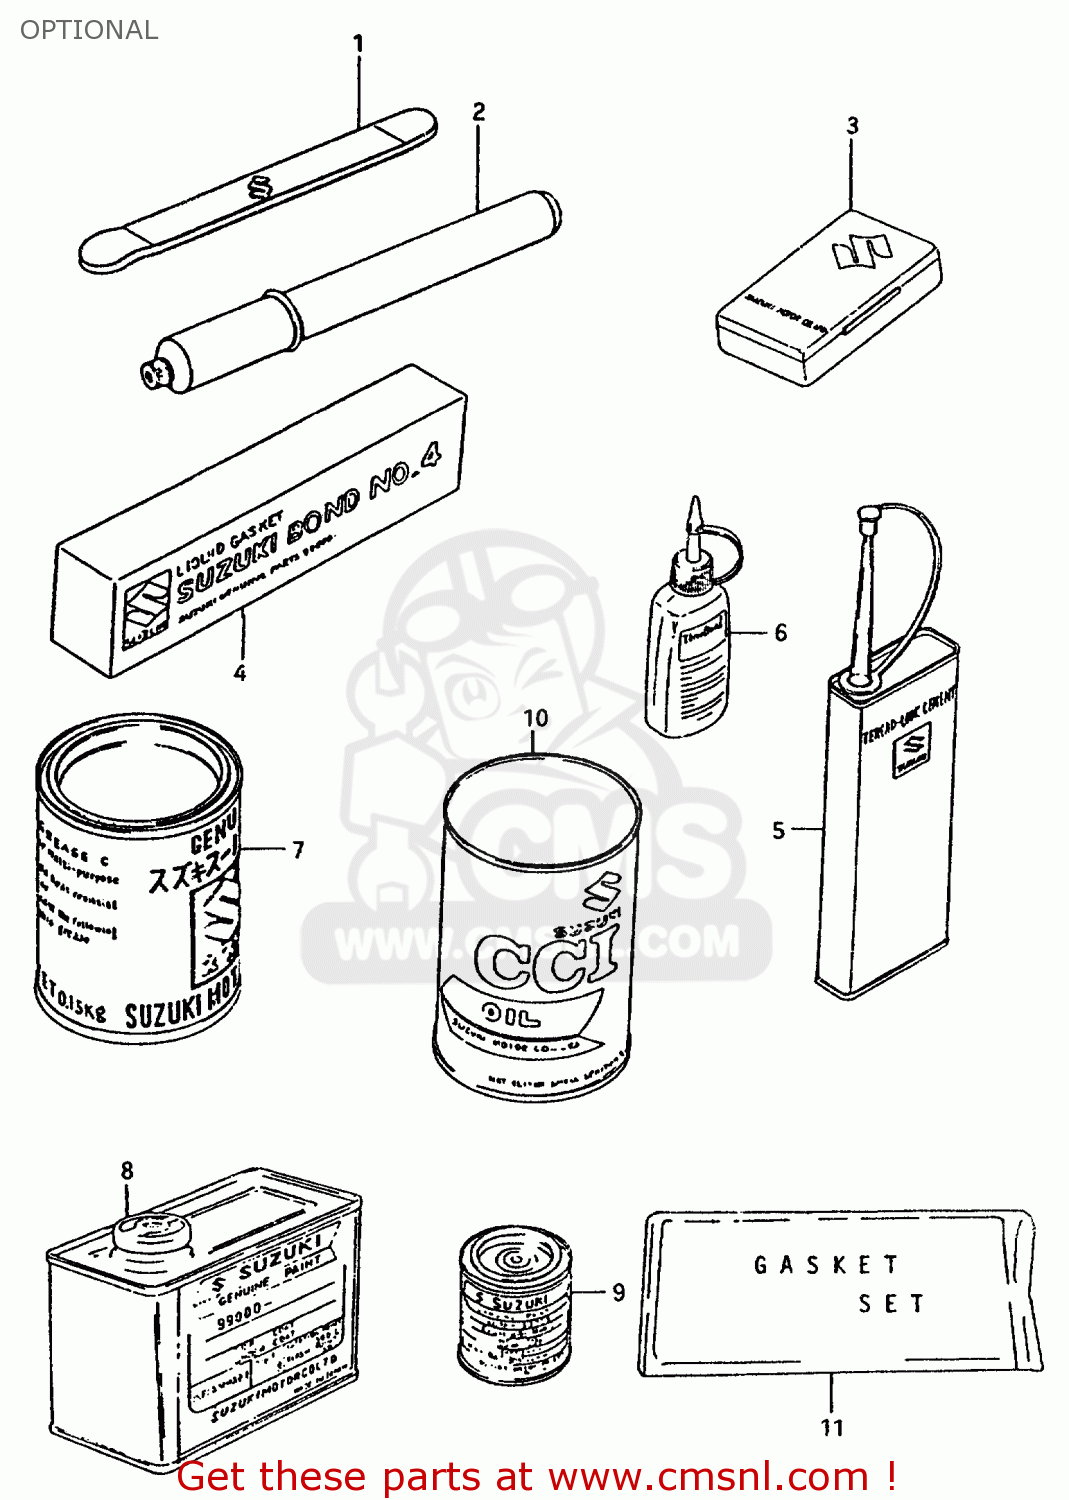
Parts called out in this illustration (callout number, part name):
1	LEVER,TIRE
2	INFLATOR, AIR
3	TUBE REPARING TOOL
4	BOND 1104
5	THREAD LOCK NO.1401 CLEAR 200G
6	THREAD LOCK NO.1303B PURPL 50G
7	GREASE(C)EP2 LITHIUM 150G
8	PAINT (BLACK)
9	PAINT,BLACK
10	CCI OIL
11	GASKET SET (MCA)
